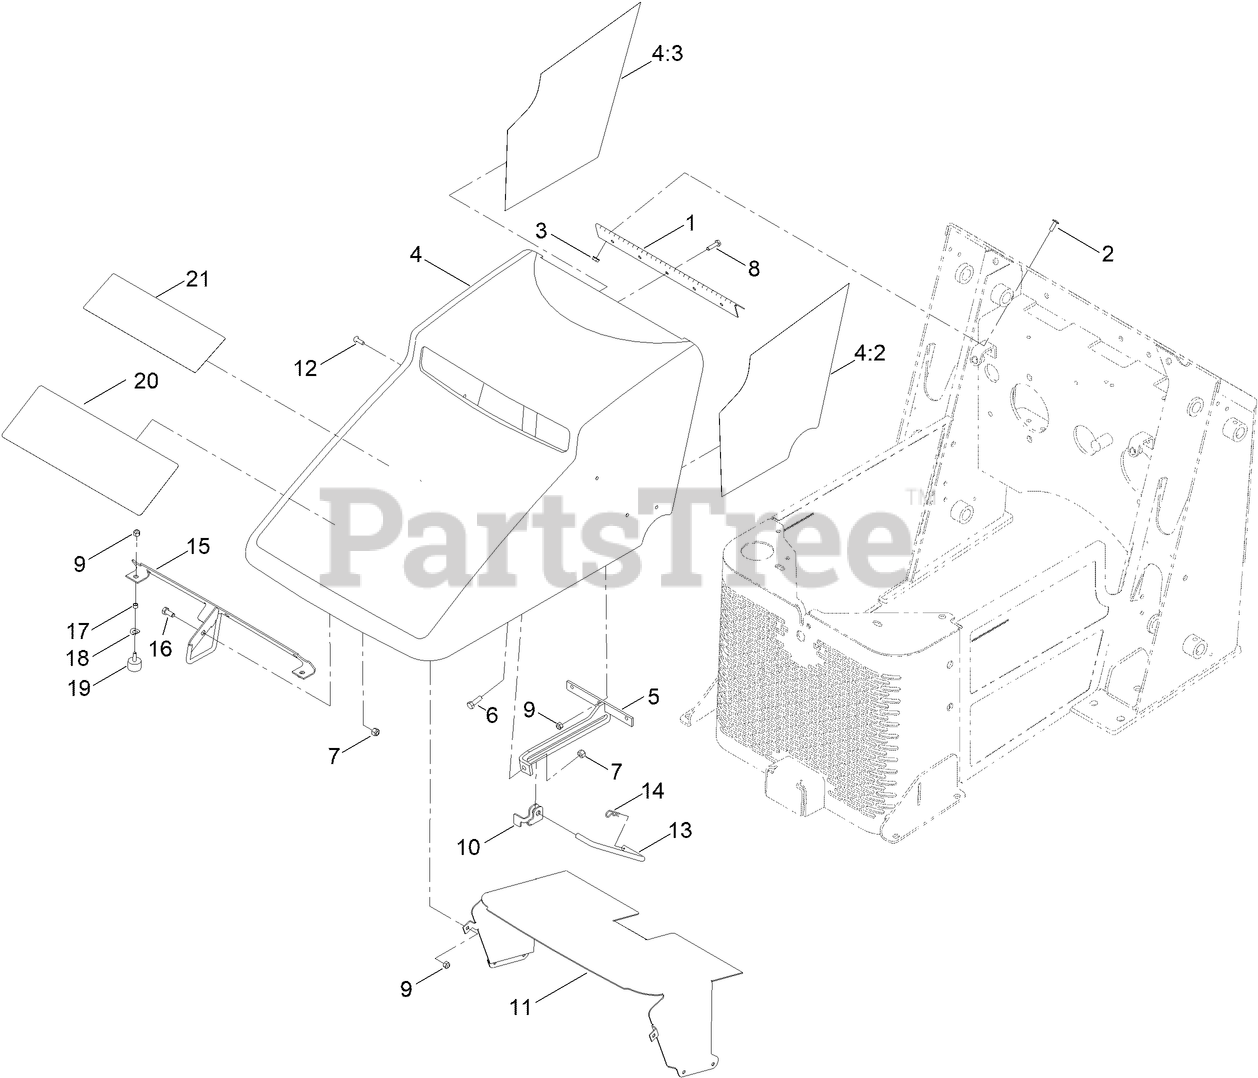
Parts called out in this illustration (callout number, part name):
1	HINGE-HOOD
2	SCREW-HEAD, TRUSS
3	NUT-HF
4:2	FOILTAPE-LH
4:3	FOILTAPE-RH
5	BRACKET-ROD, PROP
6	SCREW-HH
7	NUT-LOCK, NI
8	SCREW-HH
9	NUT-LOCK, NI
10	BRACKET-LATCH, LOCKING
11	BAFFLE-HOOD
12	SCREW-PRH
13	ROD-SUPPORT, HOOD
14	PIN-COTTER
15	ROD LATCH ASM
16	SCREW-HH
17	SPACER
18	WASHER-SPRING
19	BUMPER
20	DECAL-SERVICE, TX525 DE
20	DECAL-SERVICE, TX525 FR
20	DECAL-SERVICE, TX525 IT
20	DECAL-SERVICE, TX525 NE
20	DECAL-SERVICE, TX525 PL
20	DECAL-SERVICE, TX525 RU
20	DECAL-SERVICE, TX525 SK
20	DECAL-SERVICE, TX525 ES
21	DECAL-SRHSW4X12
